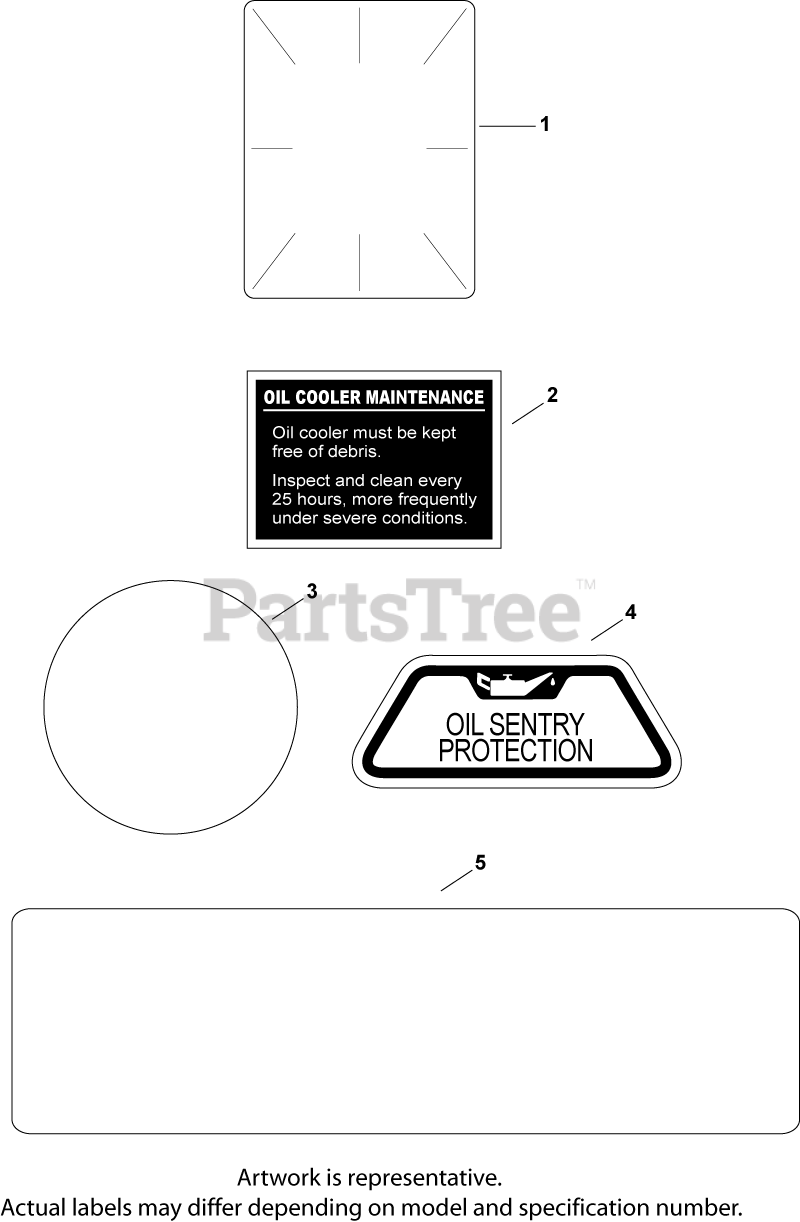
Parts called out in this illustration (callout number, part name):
1	DECAL, CLEAR LAMINATE USE 25 113 70-S
2	DECAL, OIL COOLER - (#DSC)
3	LABEL, (ROUND KOHLER GOLD)-USE 24 113 18
4	DECAL, OIL SENTRY - (#DSC)
5	DECAL, 26 HP
